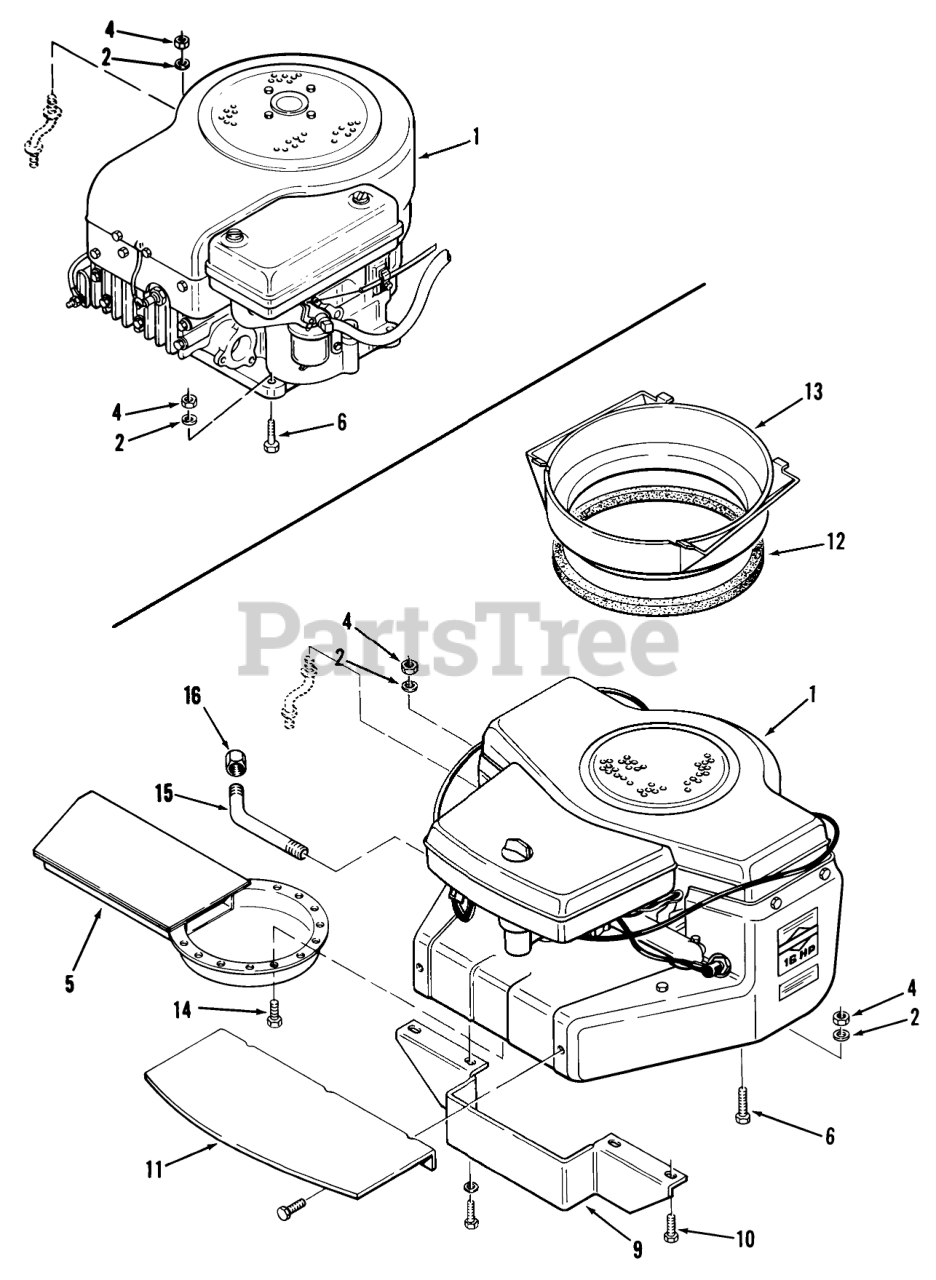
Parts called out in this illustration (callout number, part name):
1	Engine-11HP-B&S Model 252707, Type 0222-02
1	Engine-16HP-B&S Model 402707, Type 0130-03, LT-1637 Only
1	Engine-8HP-B & S Model 191707, Type 1160-02-LT-832 Only
1	Engine-10HP-Tecumseh Model TVM 220-157063D-LT-1032 Only
2	WASHER 5/16 SAE
4	Nut
5	Exhaust Deflector B-165 Only
6	Bolt
6	HHCS
9	Duct-Rear 216-5 Only
10	Bolt
11	Duct-Front 216-5 Only
12	Insulation-Hood B-165 Only
13	DUCT-AIR INTAKE
14	SCREW 8-32X3/8
16	Cap
